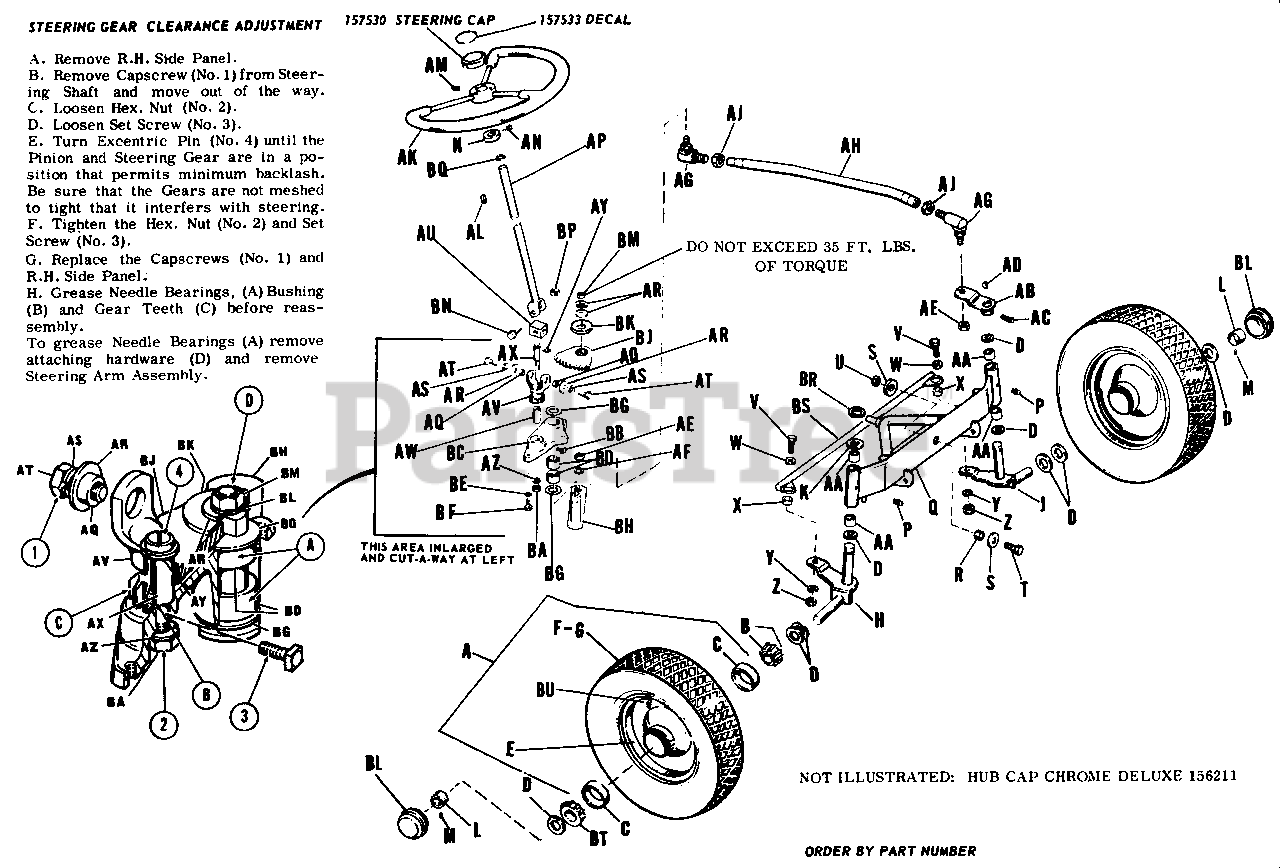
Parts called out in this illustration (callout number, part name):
A	Wheel and Tire Assembly
B	Bearing Cone, w/seal
C	Bearing Cup
E	Wheel w/Bearing Cup
G	Tube (two 16/650-8)
H	Spindle Assembly, R.H.
J	Spindle Assembly, L.H.
L	Set Collar
M	Cup Point Socket Head Set Screw, 5/16"-18 x 5/16" lg.
N	Set Collar
P	Grease Fitting
Q	Axle Assembly, Front
S	Plain Washer, 1/2"
T	Hex. Cap Screw, 1/2"-13 x 1" lg.
U	Full Lock Hex. Nut, 1/2"-13
V	Hex. Cap Screw, 3/8"-16 x 1-1/4" lg.
W	Plain Washer, 3/8"
Y	Lock Washer, 3/8"
Z	Full Hex. Nut. 3/8"-16
AB	Arm Assembly, Steering L.H.
AC	Screw Set, Cup Point, Square Head, 5/16" x 1/2" lg.
AE	Full Hex. Lock Nut 1/2"-20
AF	Lock Washer 1/2"
AJ	Nut, 1/2"-20 N.F.
AK	Steering Wheel
AL	Woodruff Key #9
AM	Socket Head Cup Point Set Screw, 5/16"-18 x 5/16" lg.
AN	Socket Hd. Set Screw, 5/16"-18 x 1/4" lg.
AP	Steering Shaft Assembly
AR	Plain Washer, 3/8"
AS	Lock Washer, 3/8"
AT	Hex Cap Screw, 3/8"-16 x 3/4" lg.
AU	Universal Joint Pin
AV	Bushing Assembly
AX	Pin Eccentric
AY	Retainer Ring
AZ	Lock Washer
BA	Full Hex. Nut 3/8"-16
BB	Sq. Hd. Set screw, 1/4"-20 x 3/4" lg.
BC	Steering Bracket
BD	Needle Bearing
BE	Lock Washer, 5/16"
BF	Hex. Cap Screw, 5/16"-18 x 5/8"
BH	Steering Arm Assembly
BJ	Gear Steering
BK	Arbor Washer
BL	Hub Cap
BM	Gripco Center Lock 5/16"-14
BN	Hex Cap Screw
BP	Full Hex. Nut, 5/16"-18
BR	Retainer Ring
BS	Drag Link
BT	Outside Bearing
BU	Valve Stem
